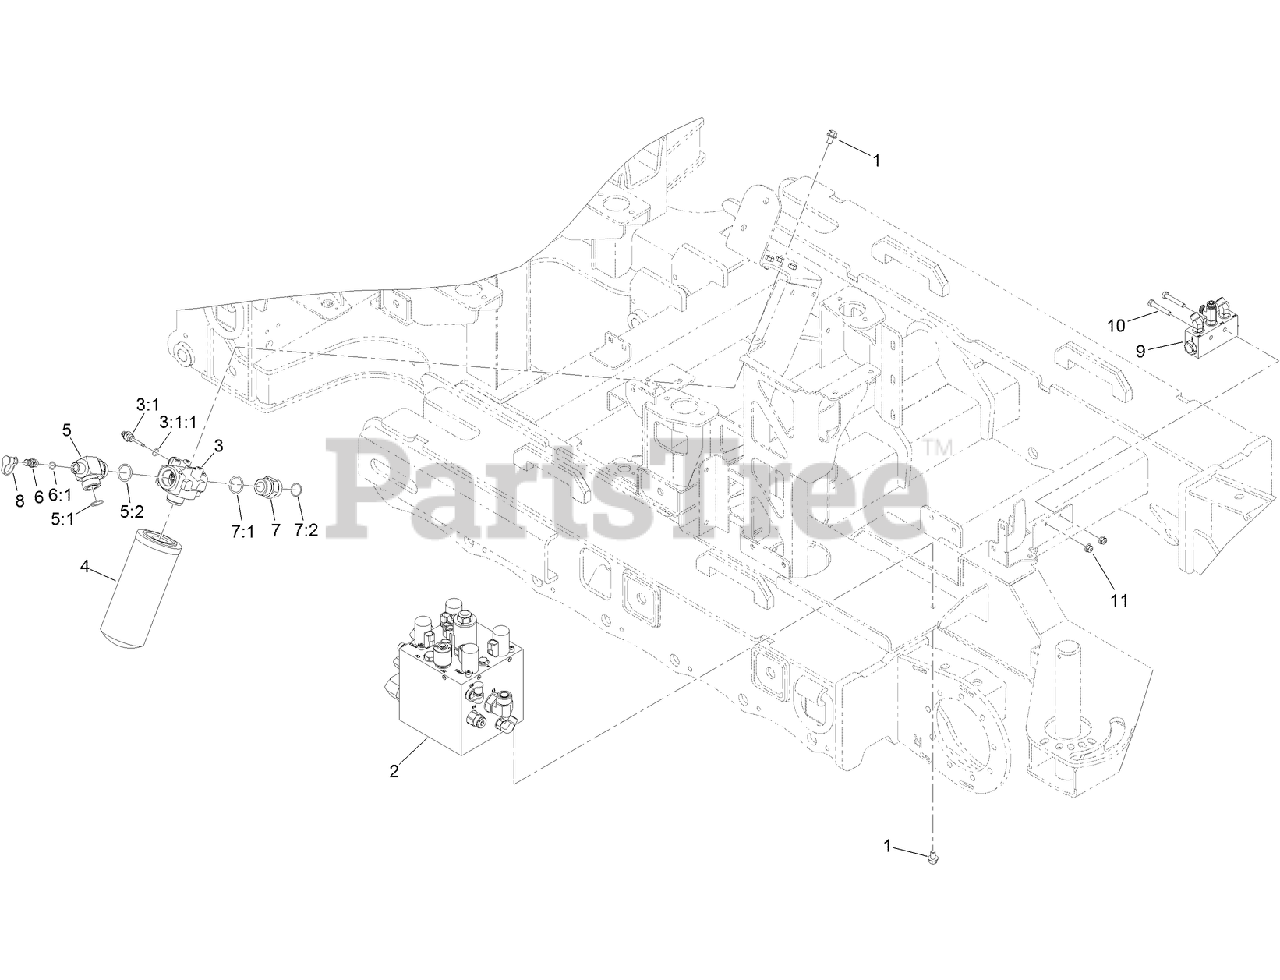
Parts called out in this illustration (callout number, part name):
1	SCREW-HHF
2	TRACTION MANIFOLD ASM
3	HYDRAULIC FILTER ASM
3:1	SWITCH-INDICATOR, ELECTRICAL
3:1:1	O-RING
4	ELEMENT-FILTER
5	FITTING-TEE
5:1	O-RING
5:2	O-RING
6	FITTING-DIAGNOSTIC
6:1	O-RING
7	FITTING-STRAIGHT
7:1	O-RING
7:2	O-RING
8	CAP-DUST
9	CHARGE CHECK MANIFOLD ASM
10	SCREW-HH
11	NUT-HF, NI
